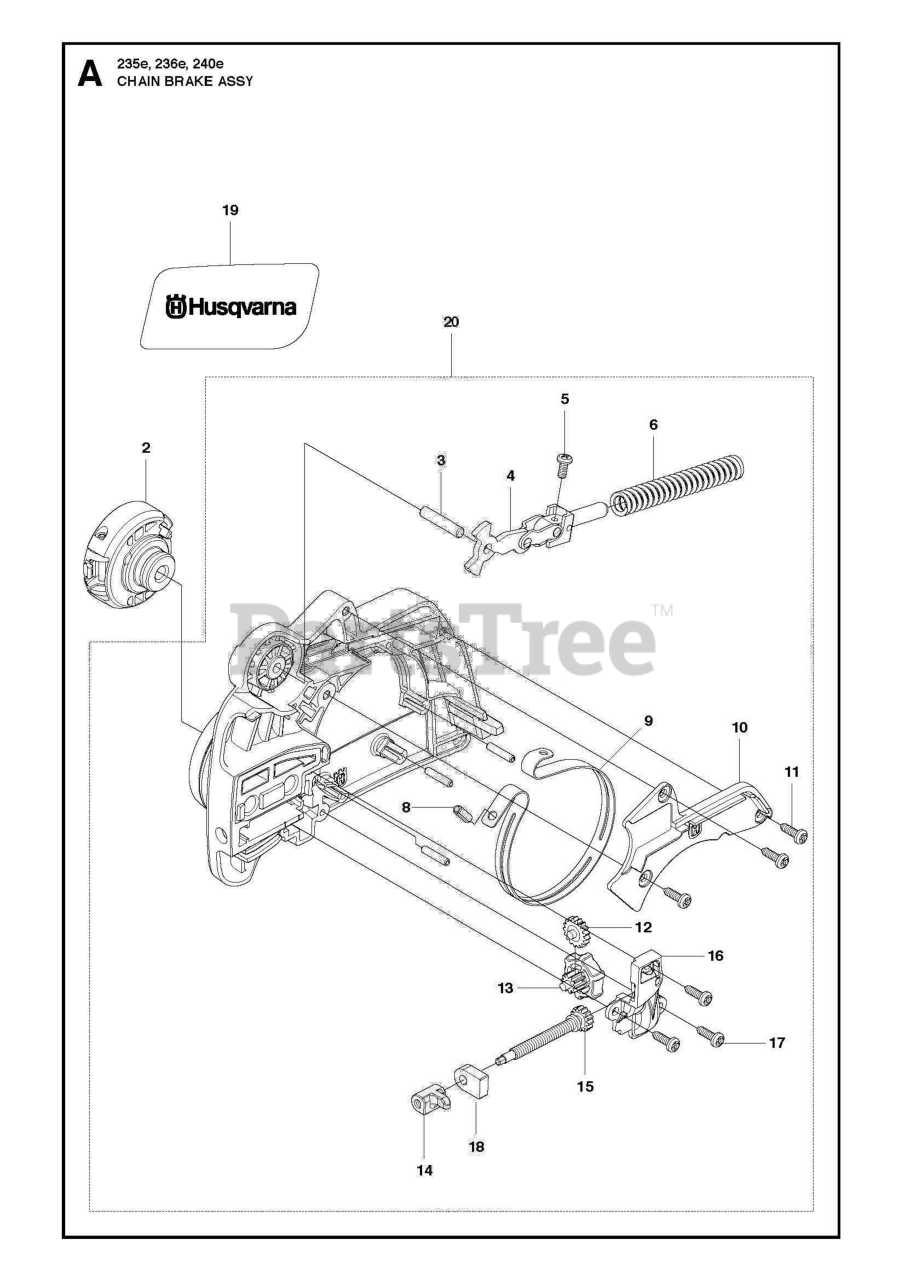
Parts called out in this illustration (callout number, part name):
4	FRONT LINK ASSY
5	SCREW M3.63-1.34 X 8MM
9	BRAKE BAND
10	COVER CHAIN BRAKE GRAY HUSQ
11	SCREW 6-19X.437
12	GEAR IDLER
13	ADJUSTMENT WHEEL
14	PIN BAR ADJUSTING EZT
16	COVER, GEAR
17	SCREW 6-19X.437
18	BEARING SLEEVE
19	DECAL, EZT CLUTCH
20	CHAINBRAKE ASSY HUSQ ORANGE
